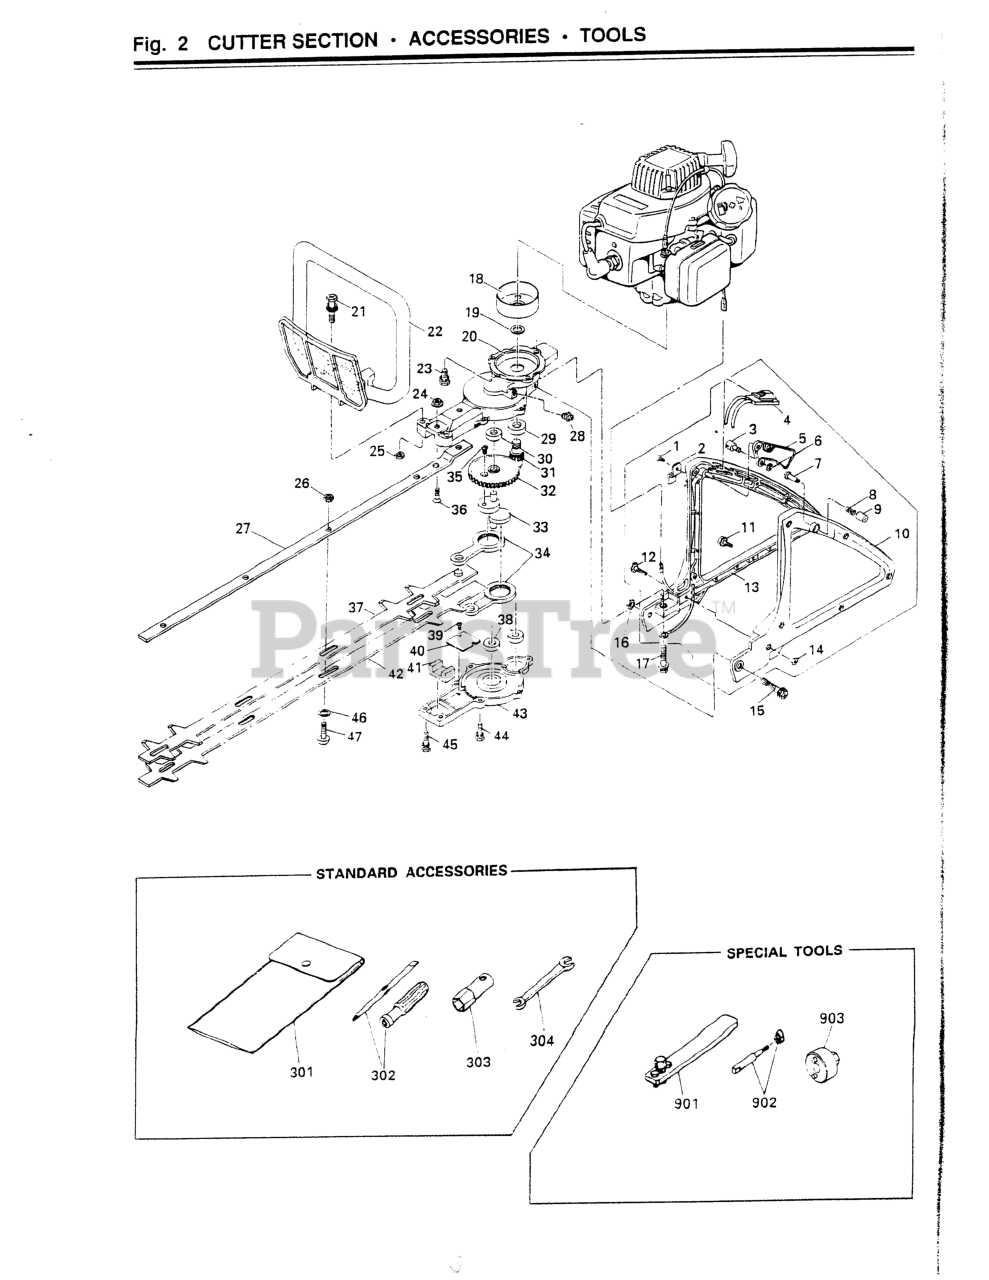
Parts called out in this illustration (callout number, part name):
1	SCREW, M4 x 10
2	PLATE
3	END, CABLE
4	SWITCH
6	RING, SNAP
8	SPRING
9	CAP, PIN
11	SCREW, M4 X 16
12	SCREW, M4 x 30
14	NUT, M6 X 4
15	BOLT, M6 X 50
16	NUT, M6 X 5
17	BOLT, M6 X 40
19	DRUM COLLAR
21	BOLT, M6 x 30
23	BOLT, M6 X 14
24	NUT
25	NUT, M6 X 5
26	NUT, M6
27	PLATE, GUIDE (USE -06020)
28	FITTING, GREASE
29	BEARING
30	BEARING (NLA)
31	PINION (NLA)
32	GEAR (NLA)
33	CRANKSHAFT (NLA)
34	ROD
35	SCREW
36	SCREW
37	BLADE, UPPER DOUBLE, 24
38	BEARING (NLA)
39	SCREW, M3 x 5
40	PLATE
41	FELT
42	BLADE, LOWER DOUBLE, 24
43	CASE, LOWER
44	BOLT, M5 x 16
45	BOLT, M5 X 20
302	SCREWDRIVER
303	SOCKET, HEX, 3/4
902	(H) ROD ASSY
903	WRENCH (TOOL)
